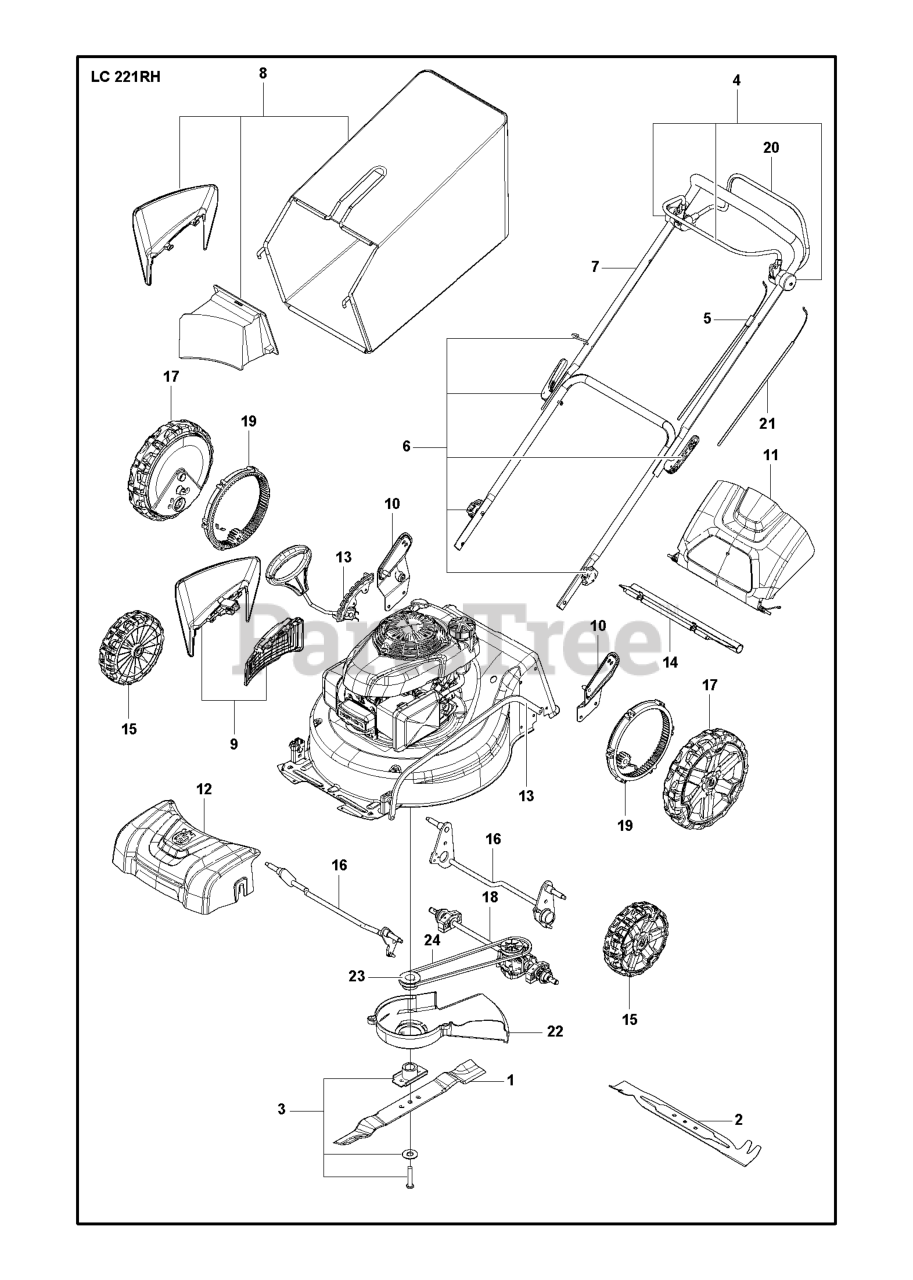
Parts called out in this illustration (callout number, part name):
6	Handles
8	Grass Bags
18	Transmissions
